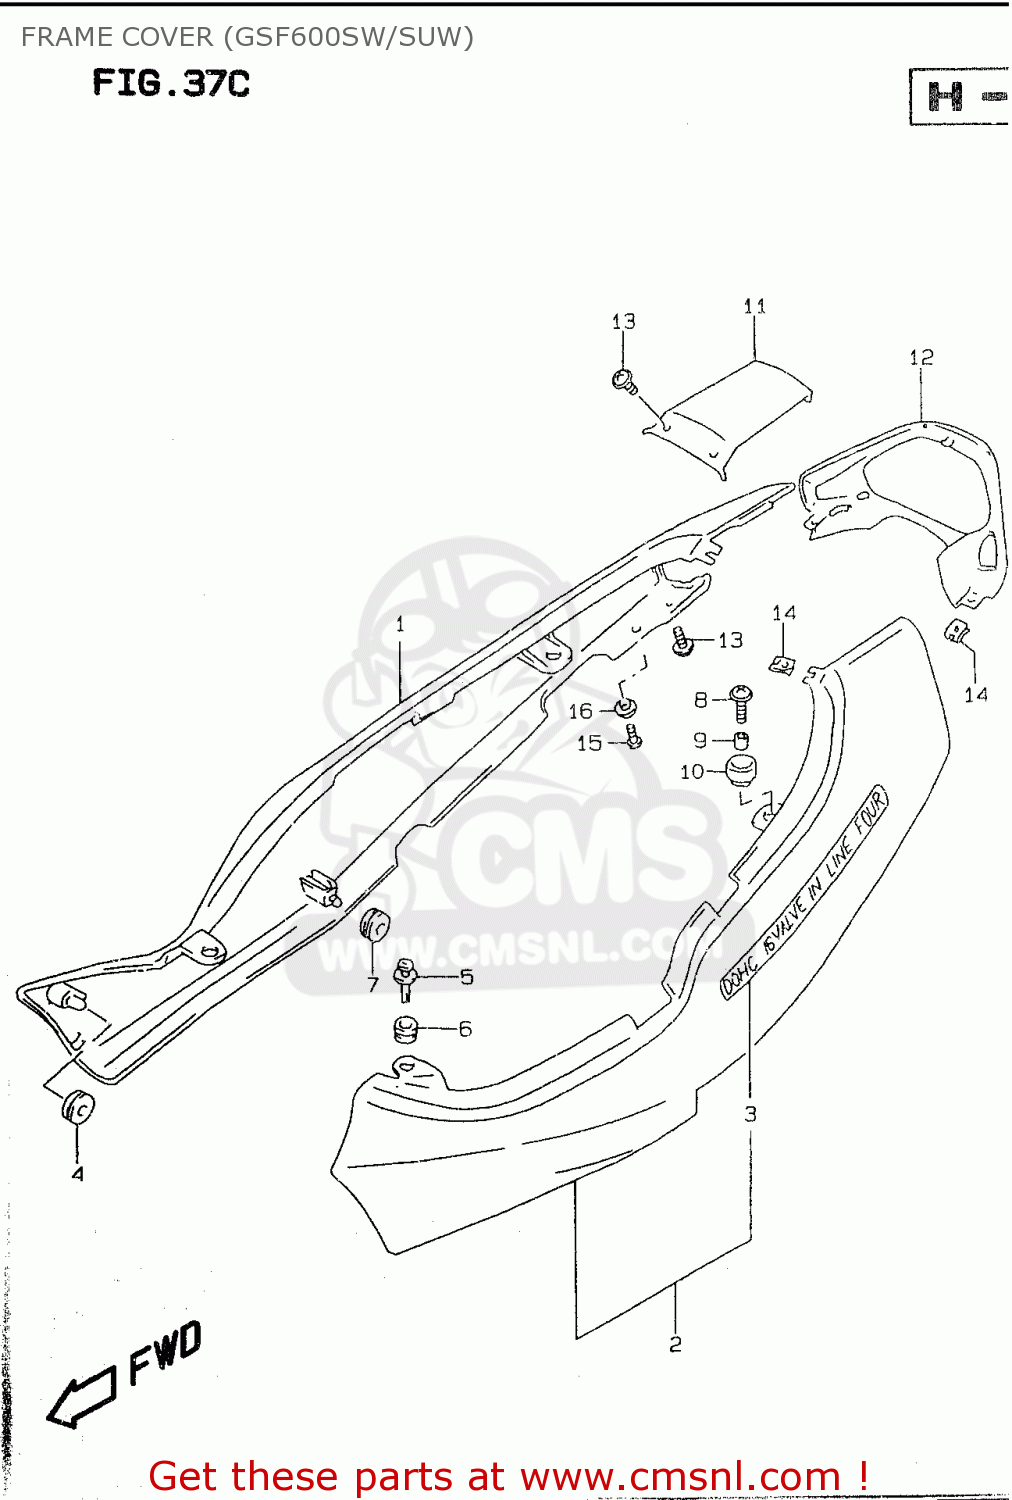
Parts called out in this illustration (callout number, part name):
1	COVER,FRAME,R(GREEN)
2	COVER,FRAME,L(GREEN)
3	EMBLEM,FRAME COVER
4	CUSHION,FRAME COVER FR
5	CLIP
6	CUSHION
7	CUSHION
8	SCREW(6X20)
9	SPACER(6.5X10X9.4)
10	CUSHION
11	COVER,FRAME,CENTER
12	COVER,FRAME RR
13	SCREW
14	NUT
15	SCREW
16	WASHER(6.3X16X1.5)
